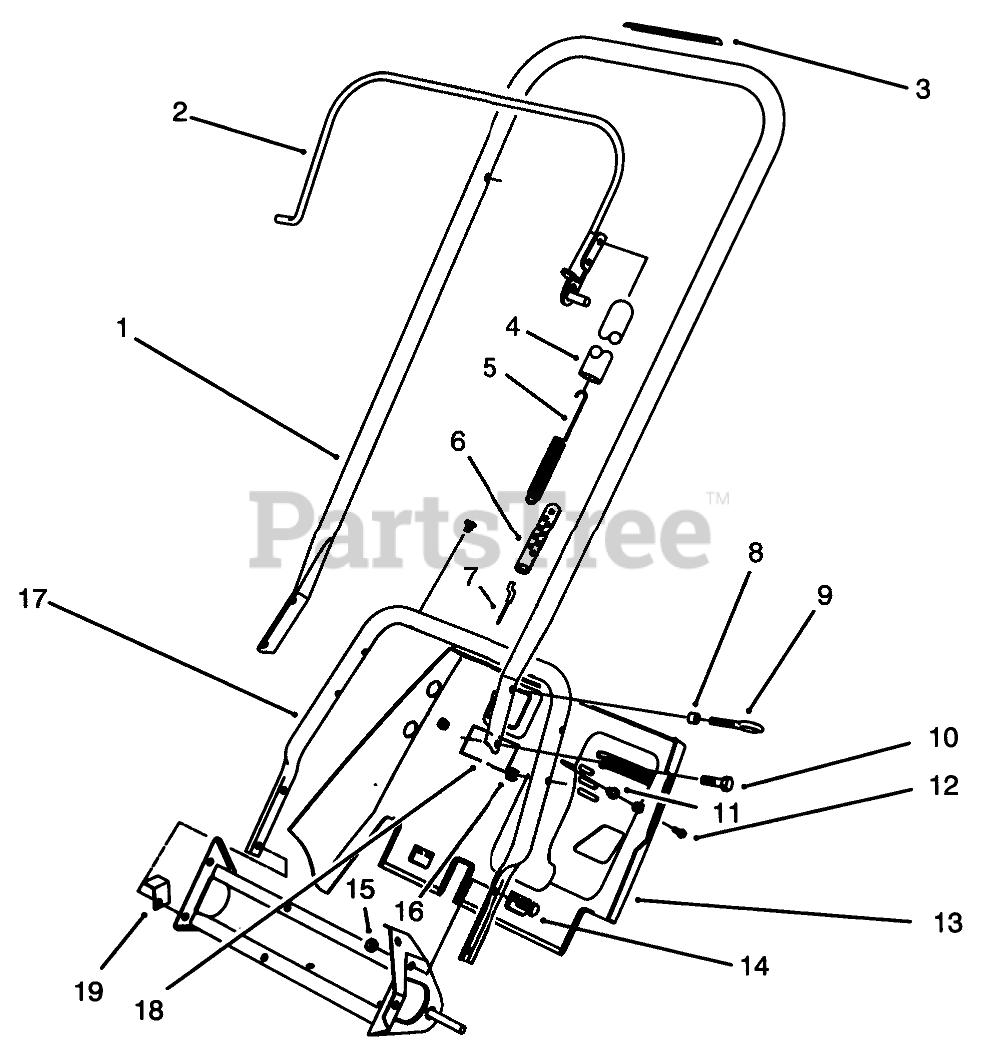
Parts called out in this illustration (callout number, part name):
1	Handle-Upper
2	Bail
3	DECAL - ROTOR DRIVE
4	COVER-SPRING
5	SPRING-CLUTCH
6	ADJUSTER-CABLE, CLUTCH
7	CABLE-CLUTCH
8	SPACER-BLADE, ROTOR
9	EYEBOLT
10	SCREW-HEX HD SLOT
11	EXPANSION TYPE FASTENER
12	SCREW-SHWH, THREAD FORMING
13	LOWER SHROUD
14	SCREW-HH
15	NUT-LOCK, NI
16	TINNERMAN NUT
17	Handle-Lower
18	DECAL
19	SHROUD BRACKET
